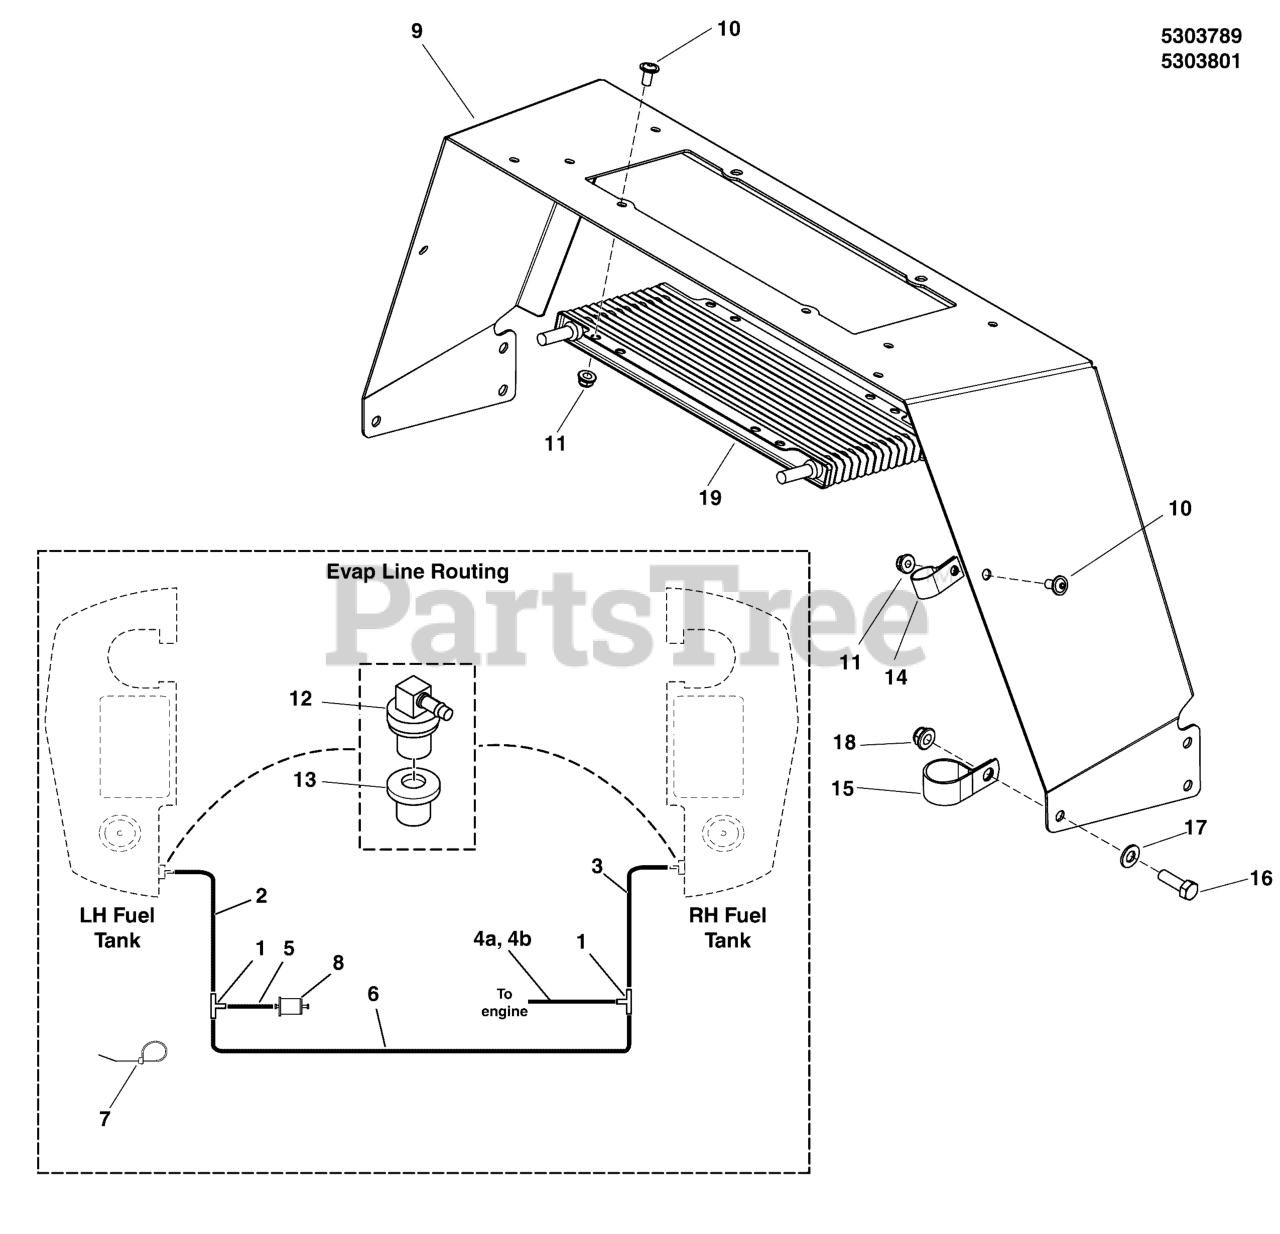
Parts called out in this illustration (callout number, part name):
1	FITTING, 3/16" TEE, BARB TYPE, HDPE
2	HOSE, VAPOR, 5MM ID, 19.50 LG
3	HOSE, VAPOR, 5MM ID, 30.00 LG
5	HOSE, VAPOR, 5MM ID, 2.00 LG
6	HOSE, VAPOR, 5MM ID, 3.50 LG
7	TIE,SELF-LOCKING, 6"
8	FILTER, FUEL
9	MOUNT, OIL COOLER/CARB CANISTER - BLK
10	SCREW, 1/4-20 X 1/2 ALLEN BH
11	NUT, 1/4-20 HEX NYLOCK FLANGE
12	REMOTE VENT ASSEMBLY
13	GROMMET
14	CLAMP, VINYL COATED, 5/8 ID
15	CLAMP, HOSE, 1.000 DIA.
16	BOLT, 5/16-18 X 1 GD5 YZ
17	WASHER, 5/16" SAE
18	NUT, 5/16-18 HEX NYLOCK FLANGE
19	OIL COOLER, .75 X 11.0 X 24 PLATES
